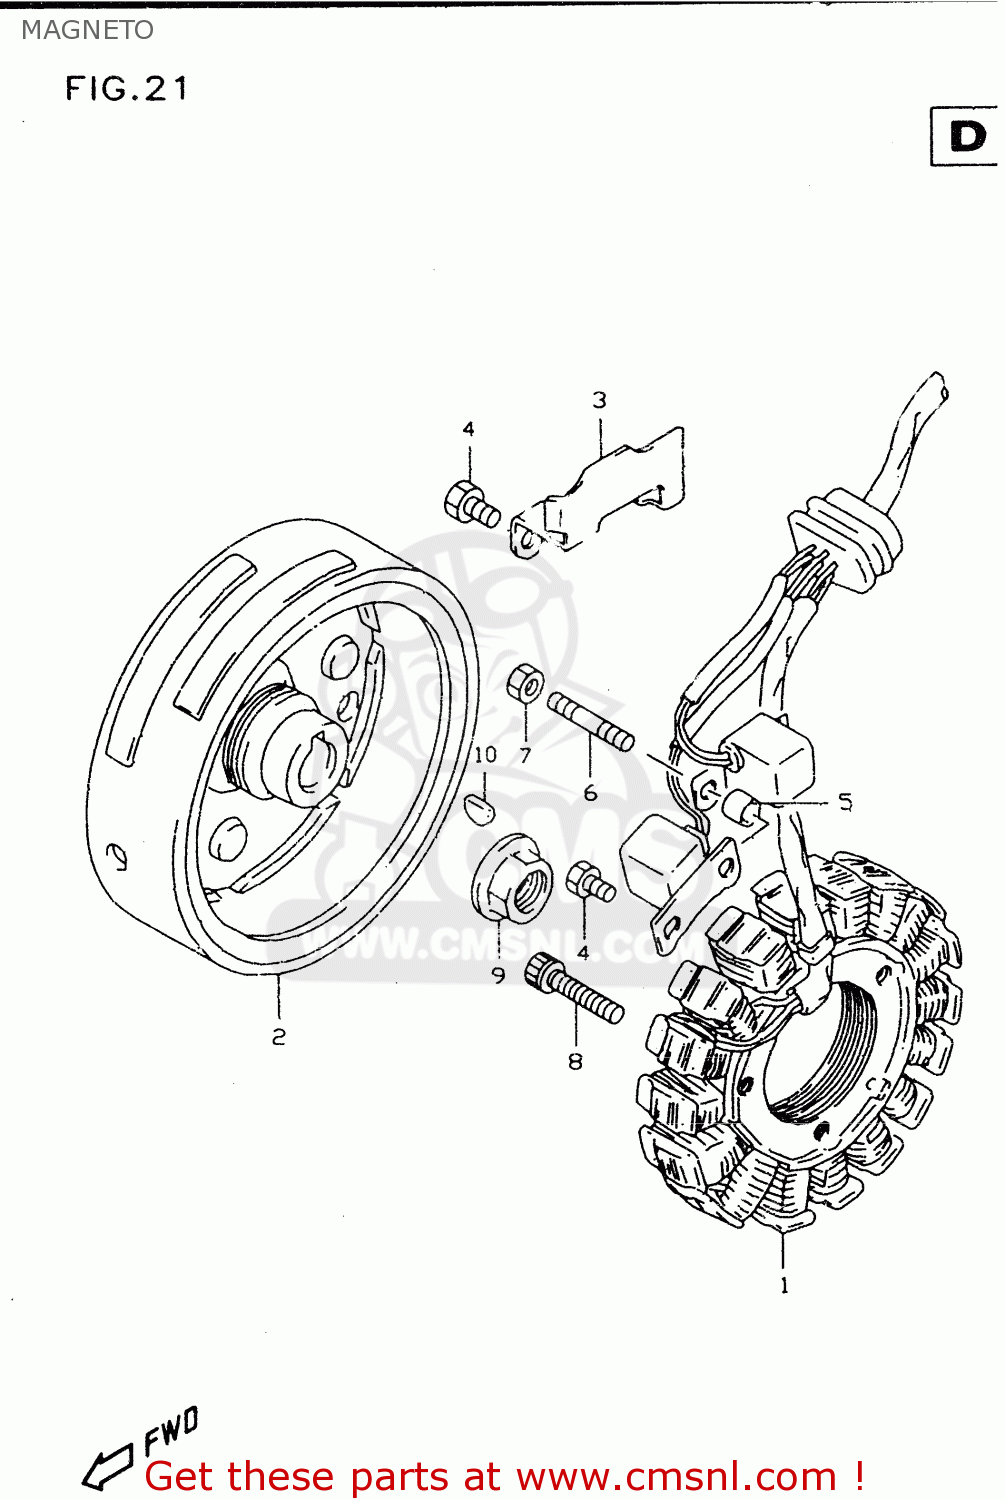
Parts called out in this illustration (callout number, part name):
1	STARTER ASSY
2	ROTOR ASSY
3	CLAMP,MAGNETO LEAD WIRE
4	BOLT(5X10)
5	SPACER(5.5X9.5X6.5)
6	BOLT,STUD(5X18)
7	NUT
8	BOLT,CL.COVER
9	NUT
10	KEY
